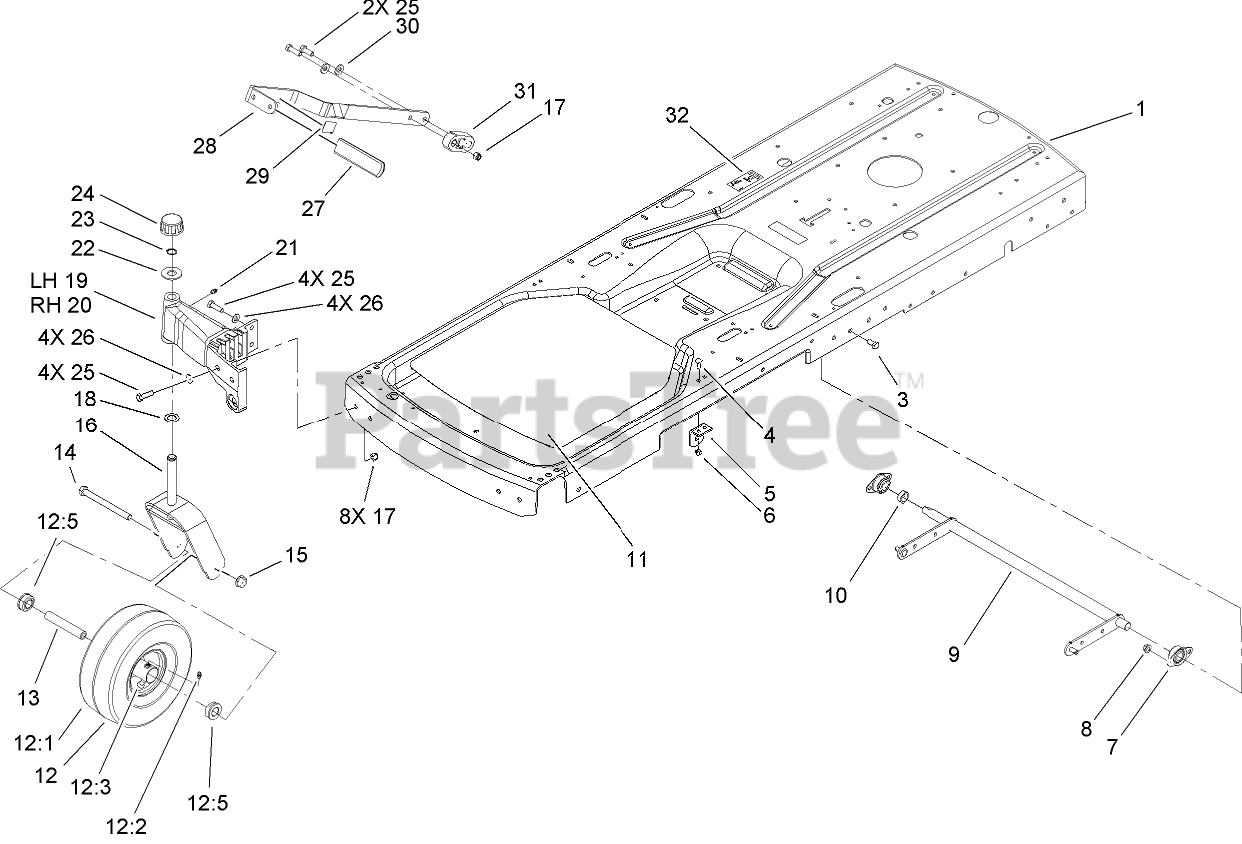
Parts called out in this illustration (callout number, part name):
3	SCREW-HH
4	BOLT-CARR
5	BRACKET-LIFT
6	NUT-LOCK, NI
7	BEARING-FLANGE, SIDE
8	NUT-HHF, WHIZ
9	LIFT ARM ASM
10	SPACER
11	PAD-ANTISKID
12	FRONT WHEEL AND TIRE ASM
12:2	FITTING-GREASE
12:3	STEM-VALVE
12:5	BUSHING-FLANGE
13	BUSHING-SPANNER
14	SCREW-HH
15	NUT-HF
16	CASTER FORK ASM
17	NUT-LOCK, NI
18	WASHER-THRUST
19	CASTER-LH
20	CASTER-RH
21	FITTING-GREASE
22	WASHER-PLAIN
23	RING-RETAINING, EXT
24	CAP-HUB
25	SCREW-HH
26	WASHER-FLAT
27	GRIP-LEVER, LIFT
28	LEVER-LIFT
29	DECAL-HOC
30	WASHER-BELLEVILLE
31	BLOCK-LIFT
32	DECAL-TRANSPORT, CE
